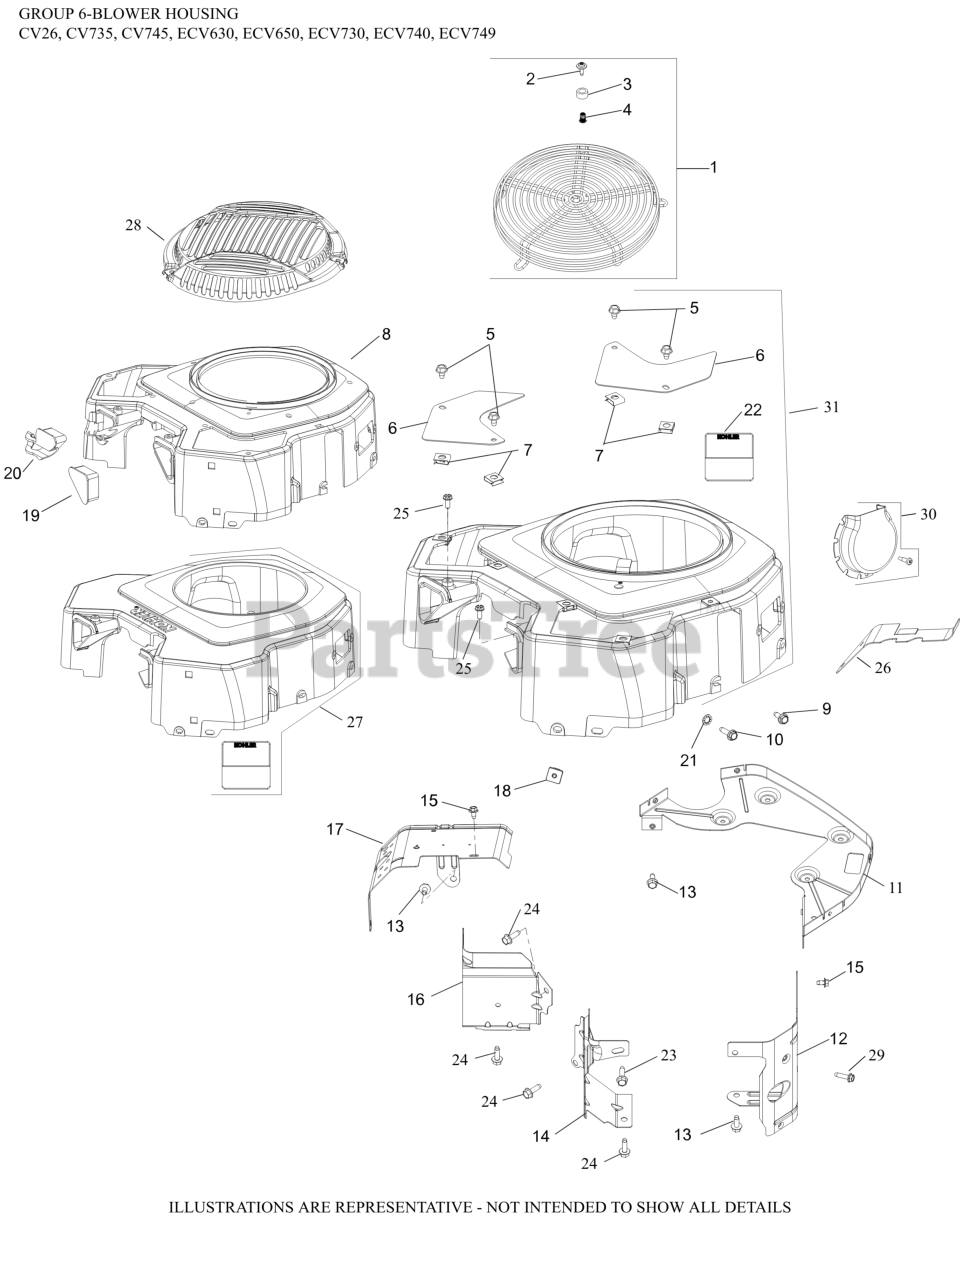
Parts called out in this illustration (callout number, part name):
2	SCREW, SEMS
4	INSERT, THREADED (M5)
5	SCREW, THREAD FORMING
6	KIT, ACCESS PANEL
7	CLIP, BAFFLE MOUNTING
8	HOUSING, BLOWER
9	SCREW, THREAD FORMING
11	PLATE, BACKING
11	KIT, BACKING PLATE
12	BAFFLE LEFT BARREL
13	SCREW, THREAD FORMING
14	BAFFLE, VALLEY #2 CYLINDER
15	SCREW, THREAD FORMING
16	BAFFLE, VALLEY #1 CYLINDER
17	KIT, RIGHT BARREL
18	NUT, PLASTIC
19	COVER, BLOWER HOUSING
20	COVER, BLOWER HOUSING-(#24096161S)
24	SCREW, THREAD FORMING
25	SCREW, WSH HD TAP #8-18X1/2"
28	GUARD, GRASS SCREEN (METAL)
